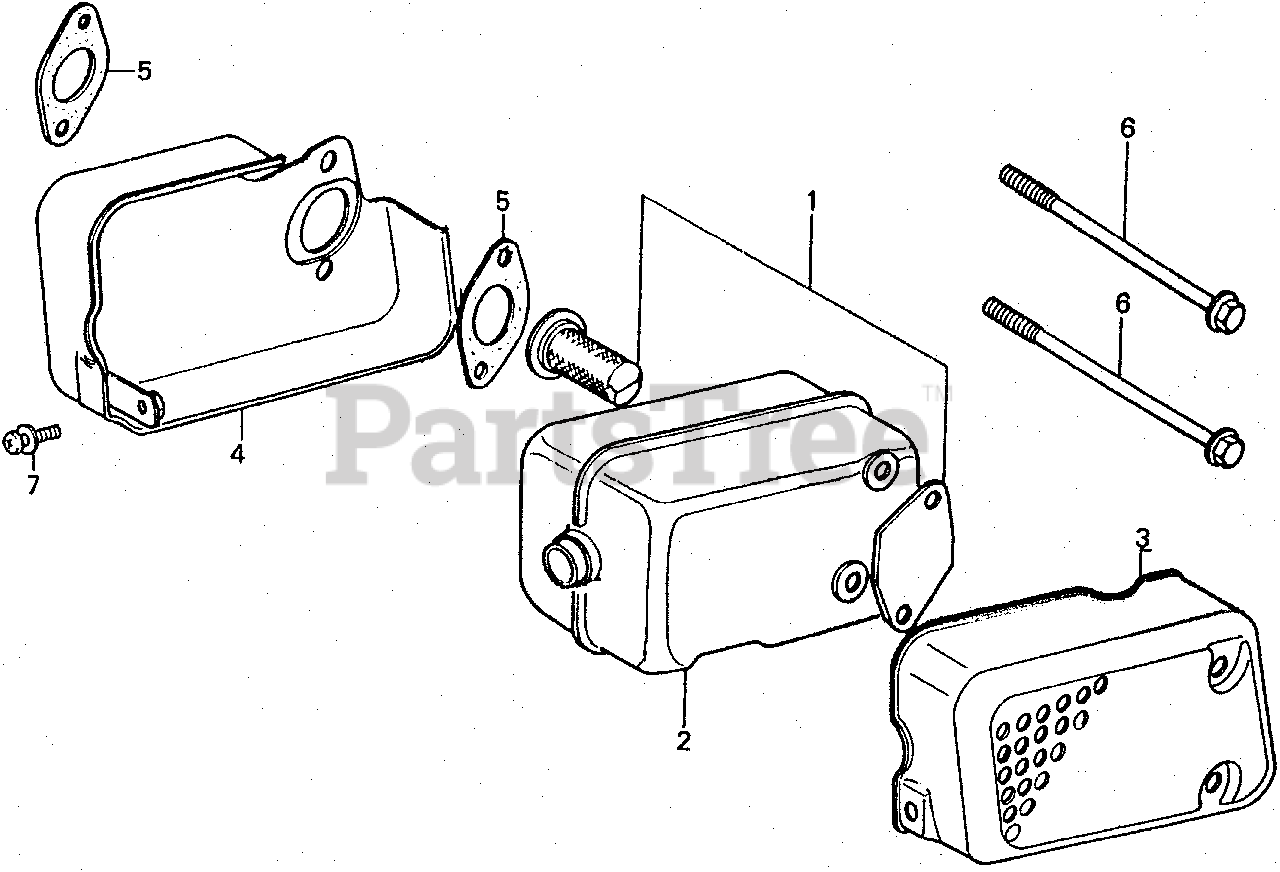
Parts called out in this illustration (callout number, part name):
1	ARRESTER KIT, SPARK
2	MUFFLER
3	PROTECTOR, MUFFLER (NOT AVAILABLE)
4	SEPARATOR, MUFFLER (NOT AVAILABLE)
5	GASKET, MUFFLER
6	BOLT, FLANGE (8X104)
7	SCREW-WASHER (5X10)
